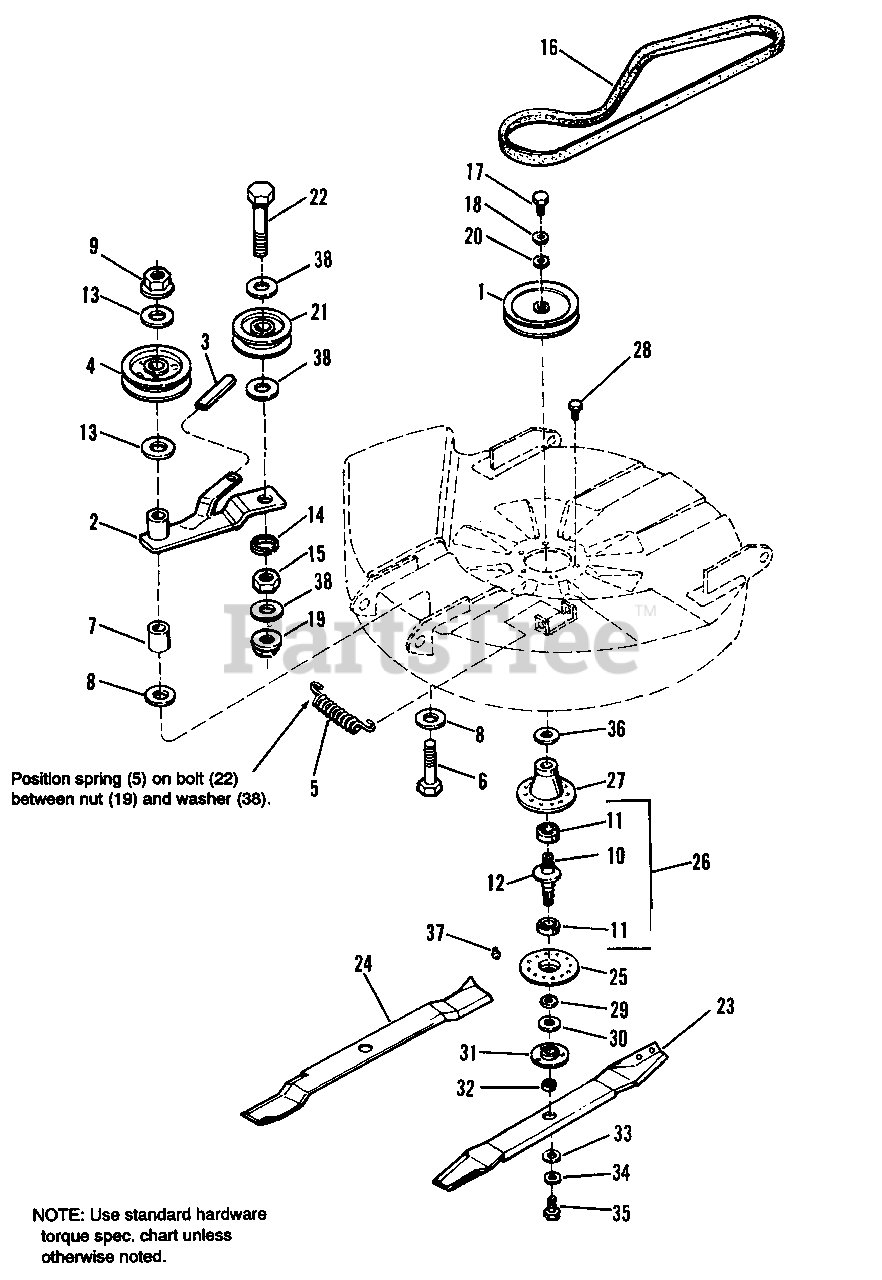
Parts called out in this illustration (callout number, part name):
1	PULLEY ASSY., 7-55/64" Dia.
2	LEVER ASSY.
3	GRIP, Lever
4	PULLEY ASSY., Idler, 6" Dia.
6	CAPSCREW, Hex, 3/8-16 x 3
8	WASHER, Flat, 3/8 x 1-1/2 x 1/8
9	NUT, Hex, Whizlock, 3/8-16
10	SHAFT, Arbor (Incl. Ref. No. 32)
12	GASKET, Foam
13	WASHER, Plain, 3/8
14	LOCKWASHER, 3/8
15	NUT, Hex, 3/8
16	V-BELT
17	CAPSCREW, Hex Hd., 7/16-14 x 1-1/2, Gr. 8
18	LOCKWASHER, 7/16
19	NUT, Hex, Top Lock, 3/8-16
20	WASHER
21	IDLER, Backside
22	CAPSCREW, Hex Hd., 3/8-16 x 2
23	BLADE, Mower (30")
24	BLADE, Mower, Mulcher (30")
25	HOUSING ASSY., Arbor, Bottom (Incl. Ref. No. 37)
26	SHAFT & BEARING ASSY. (Incl. Ref. Nos.10 & 11)
27	HOUSING ASSY., Arbor, Top
28	SCREW, Taptite, 5/16-18 x 3/4
29	WASHER, Shim
30	SHIELD, Grass, Bottom
31	ADAPTOR, Blade
32	COLLAR, Mower Arbor
33	WASHER, Spline
34	WASHER, Spring
35	CAPSCREW, Hex Hd., 7/16-14 x 1, Gr. 8
36	SHIELD, Bearing Upper, Arbor
37	GREASE FITTING
38	WASHER, Flat, 13/32 x 1 x 1/8
